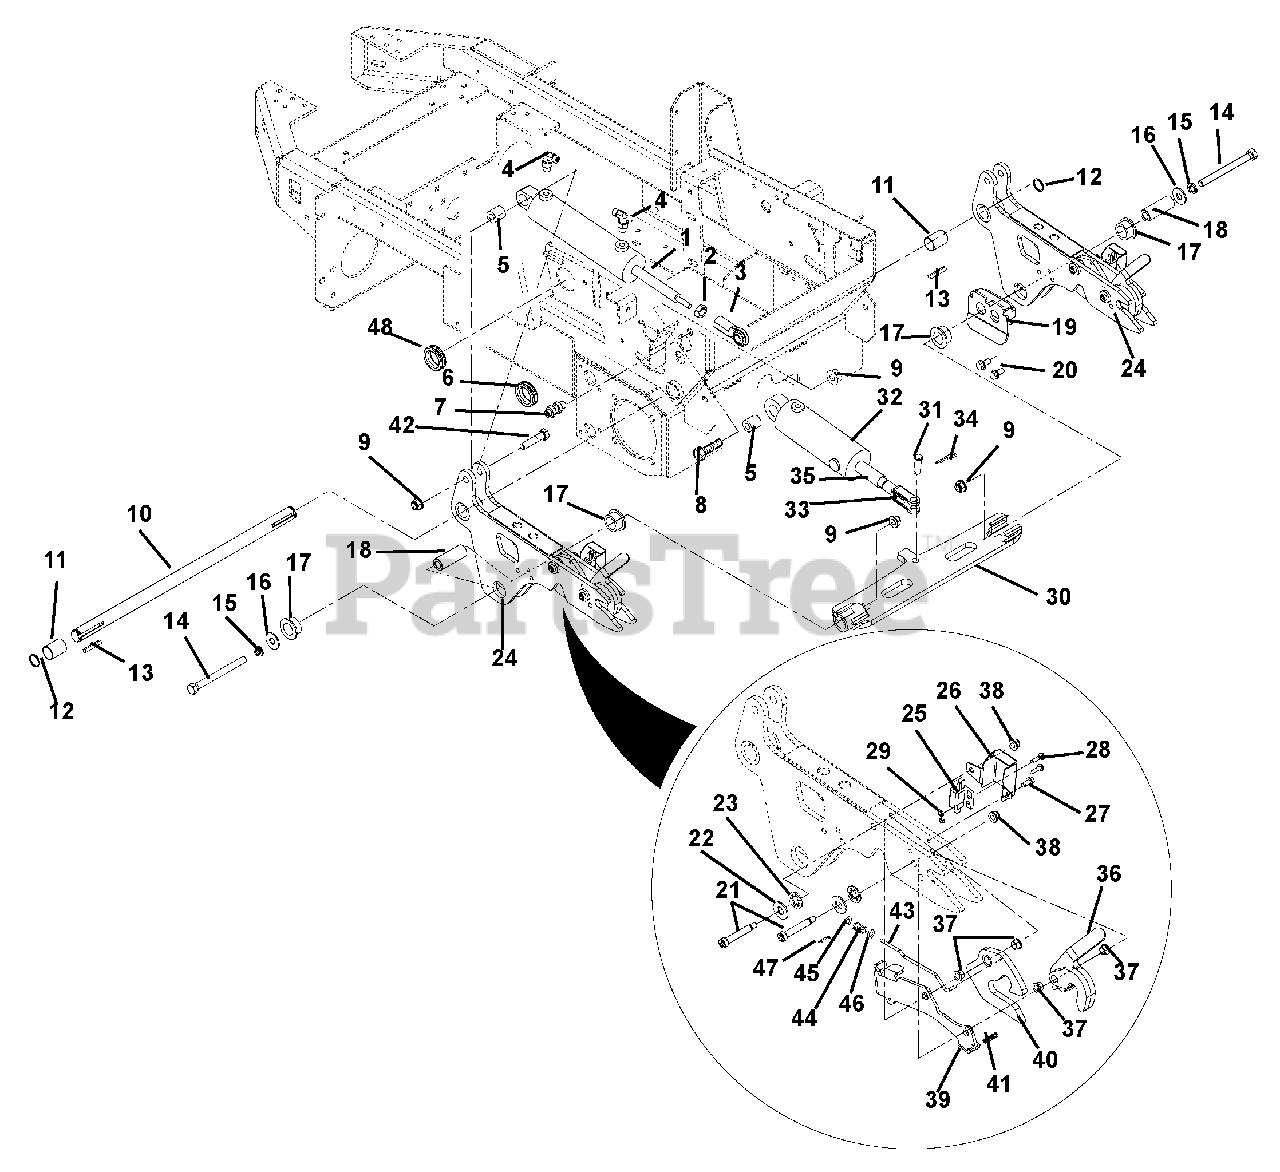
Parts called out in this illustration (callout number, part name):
1	Cylinder, Hydraulic Deck Lift
2	Nut, Jam .625-18
3	Rod End, 5/8 Right Hand- Female
4	Adapter, Hydraulic Fitting 90 M4F-M6O
5	Bushing, .516 x 1.000 x 1.050
6	Grommet, 1.25
7	Fitting,Hydraulic Bulkhead M4F-M4F
8	Bolt, Hex .50-13 x 2.25 Grade 5
9	Nut, .50-13 Nyloc Flange
10	Shaft, Main Arm Pivot
11	Bushing, 1.00 ID x 1.125 OD x 1.50
12	Ring, Retaining External 1.00 x .078
13	Key, Straight .25 x 1.75 x .25
14	Bolt, Hex .50-13 x 5.50 Grade 5
15	Washer, Locking .50 x .125 Regular
16	Washer, Flat-Steel .515 x 1.625 x .250
17	Bushing, Flange 1.020 x 1.385 x .75 x 1.75 Nylon
18	Spacer, 1.00 x .562 x 2.720
19	Weldment, Stop, Deck Block
20	Screw, Tapping .38-16 x .75 Hex Washer Head Thread Rolli
21	Bolt, Socket Head Shield .31 x 18 x 2-.38
22	Washer, Flat-Steel .406 x .812 x .065
23	Washer, Lock Internal .375
24	Weldment, Lift Arm
25	Switch, Single Pole N.O.
26	Guard, PTO Safety Switch Mount
27	Screw, Tapping .250-20 x .37 Hex Washer Head
28	Screw, Machine 10-24 x .75 Hex Washer Head
29	Nut, Locking-Nylon 10-24 with Insert
30	Weldment, Weight Transfer Bar
31	Pin, Clevis .50 x 1.33
32	Cylinder, Hydraulic 2.5 x 4.0
33	Yoke, .50-20 x 3.00
34	Pin, Hair, External- #16
35	Stud .5-20 x 2.0 Grade 8
36	Latch Lever
37	Bushing, Flange .372 x .500 x .312 x .625NY
38	Nut, .31-18 Nyloc Flange
39	Latch Support Plate
40	Latch, TILT
41	Spring, Lever Retention
42	Bolt, Hex .50-13 x 2.50 Grade 5
43	Rod, Latch Tension
44	Spring, Compression
45	Washer, Flat-Steel .281 x .62 x .065
46	Washer, Flat-Steel .38 x .875 x .083
47	Pin, Hair-Internal .06 x .18 x .77
48	Grommet, 2.00"
